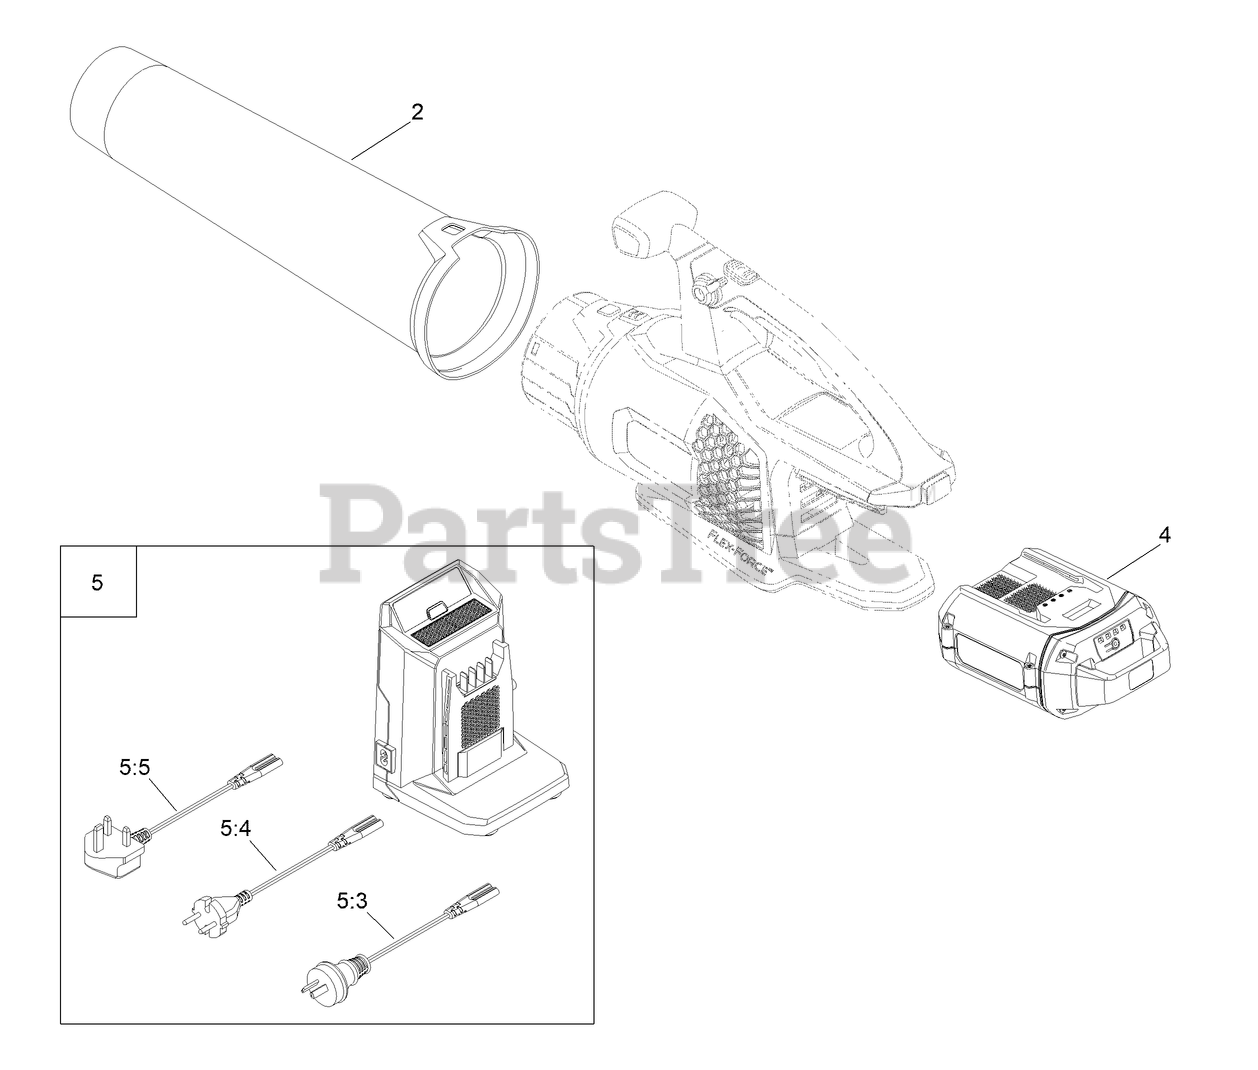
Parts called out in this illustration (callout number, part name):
2	TUBE-BLOW
4	60V 2.5AH BATTERY
5	60V CHARGER
5:3	CORD-CHARGER, AU/NZ
5:4	CORD-CHARGER, CE
5:5	CORD-CHARGER, UK
